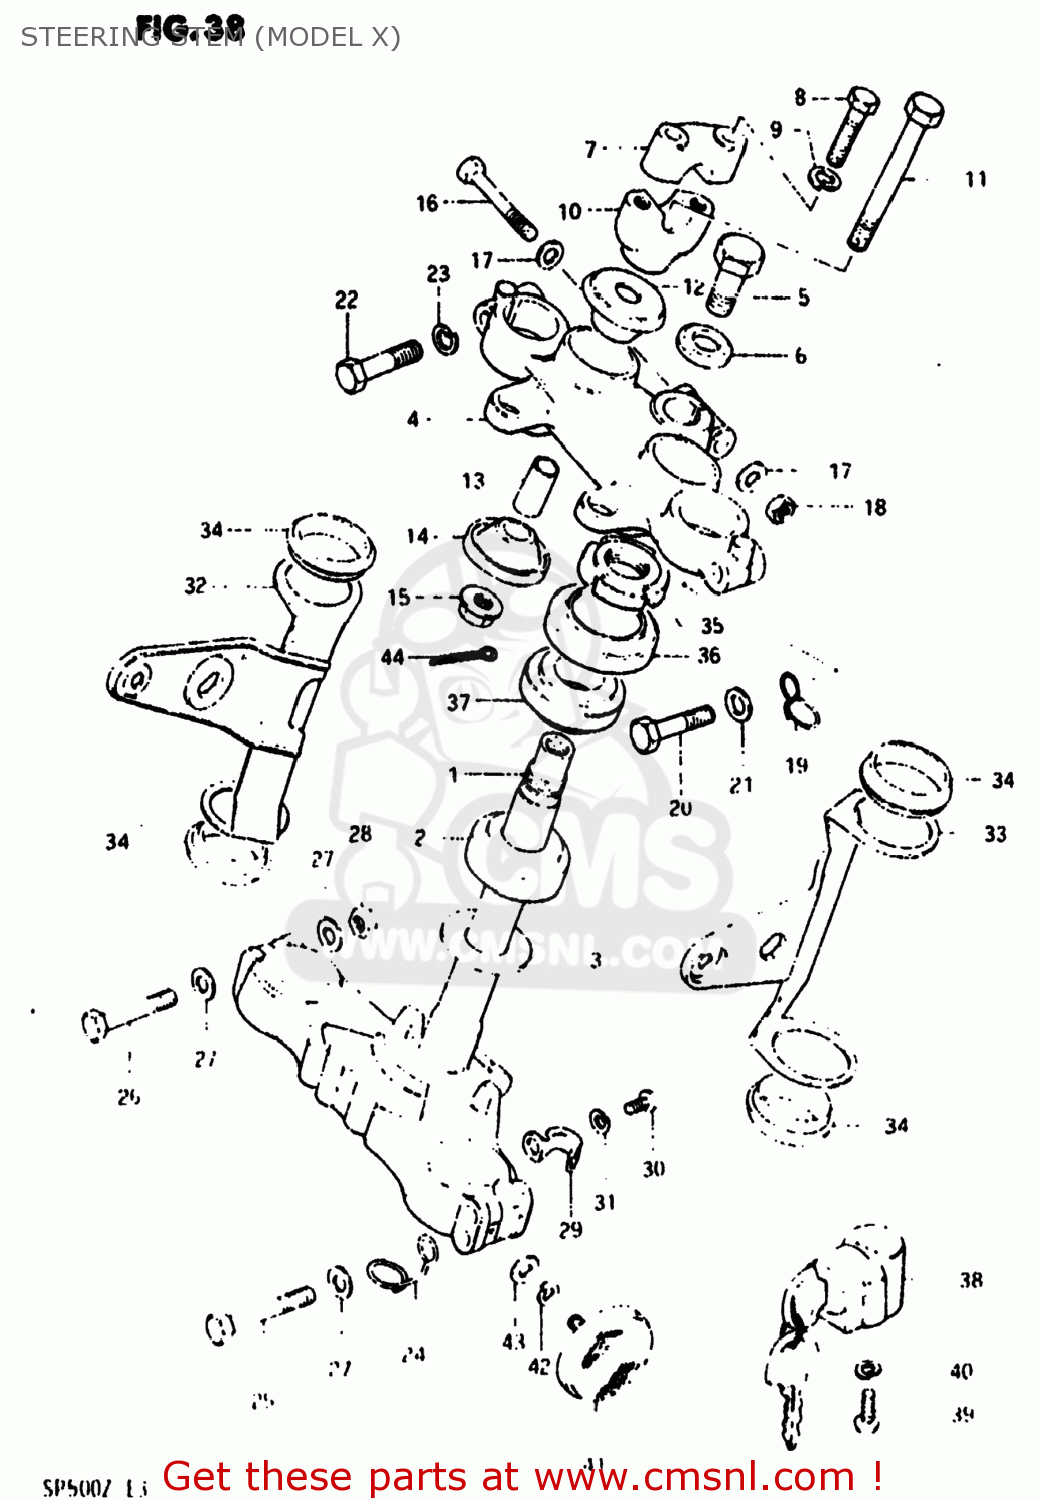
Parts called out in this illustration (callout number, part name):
1	STEM,STEERING
2	BEARING
3	WASHER,THRUST
4	HEAD,STEERING STEM
5	BOLT,STEERING STEM HEAD
6	WASHER
7	HOLDER,HANDLEBAR
8	BOLT
9	LOCK WASHER
10	HOLDER,HANDLEBAR
11	BOLT,HANDLE HOLDER
12	CUSHION,HANDLE,UPPER
13	SPACER(10.2X14X46)
14	CUSHION,HANDLE,LOWER
15	NUT
16	BOLT 8X55
17	WASHER
18	NUT
19	CLAMP,METER CABLE
20	BOLT 10X40
21	WASHER
22	BOLT 10X40
23	LOCK WASHER
24	GUIDE,CABLE
25	BOLT
26	BOLT 8X55
27	WASHER
28	NUT
29	CLIP,BRAKE CABLE
30	SCREW
31	LOCK WASHER
32	BRACKET,HEADLAMP,RIGHT
33	BRACKET,HEADLAMP,LEFT
34	CUSHION,HEADLAMP BRACKET
35	NUT,STEERING STEM(25X44X10)
36	DUST SEAL,STEERING,UPPER
37	TAPER,ROLLER BEARING
38	LOCK ASSY,STEERING
39	SCREW
40	LOCK WASHER
41	REFLEX REFLECTOR,FR
42	LOCK WASHER
43	WASHER
44	PIN 20X20
